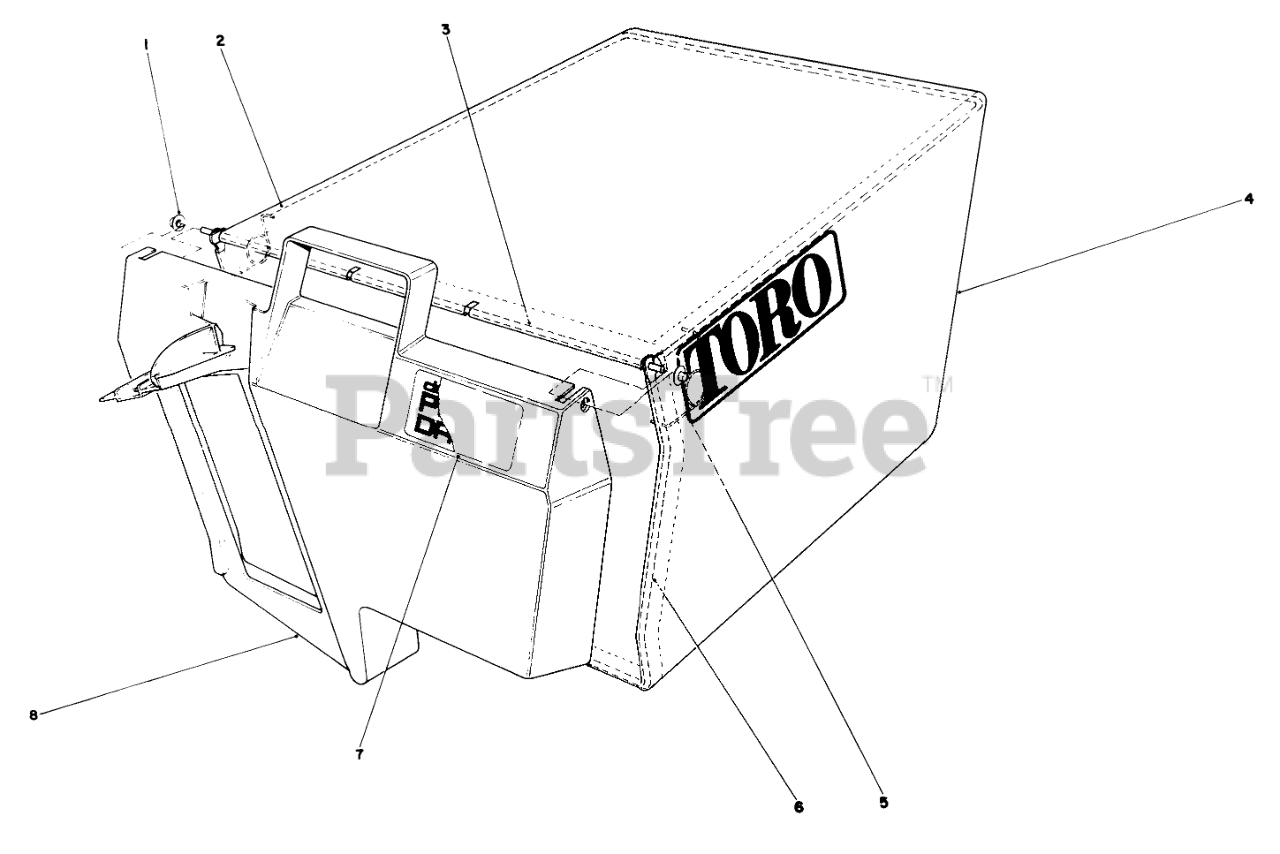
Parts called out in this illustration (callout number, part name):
1	NUT-PUSH
2	FRAME-BAG, UPPER
3	HINGE-DOOR, BAG
4	BAG-GRASS
5	SPRING
6	FRAME-BAG
7	BAG DOOR DECAL
8	DOOR-BAG
